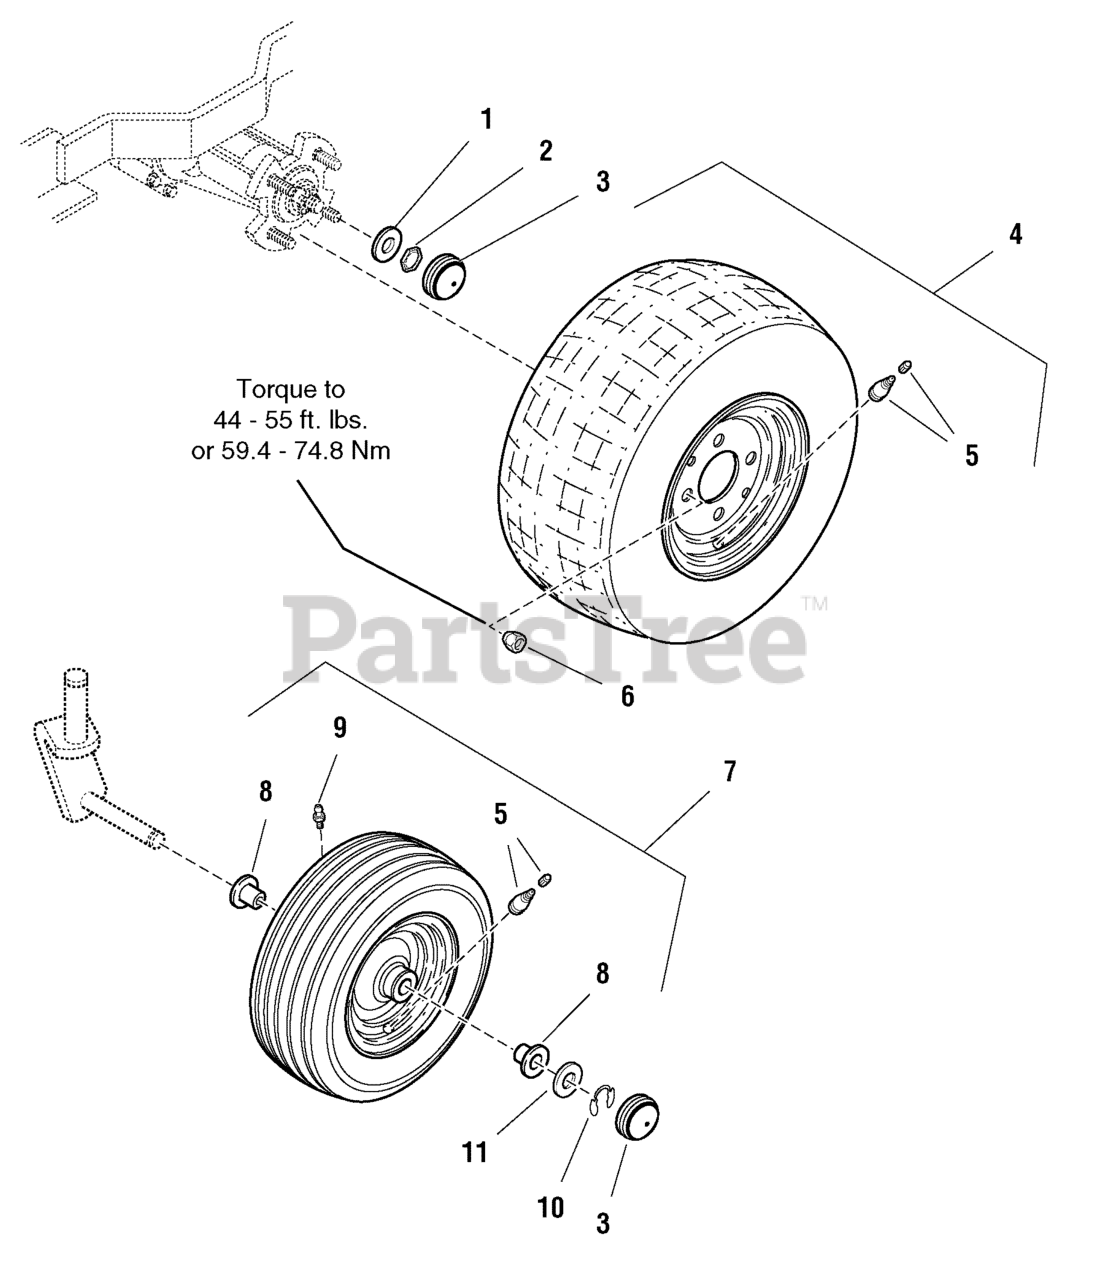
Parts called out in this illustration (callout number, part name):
2	NUT, Hex Lock PAL, 3/4-20
3	CAP, Hub
4	WHEEL & TIRE ASSEMBLY, Rear
5	VALVE STEM & CAP
6	NUT, Hex Lug, 1/2-20
7	WHEEL & TIRE ASSEMBLY, Front
8	BUSHING, Wheel
9	FITTING, Lube
10	RING, Klipring for 3/4 Shaft
11	WASHER, 3/4
